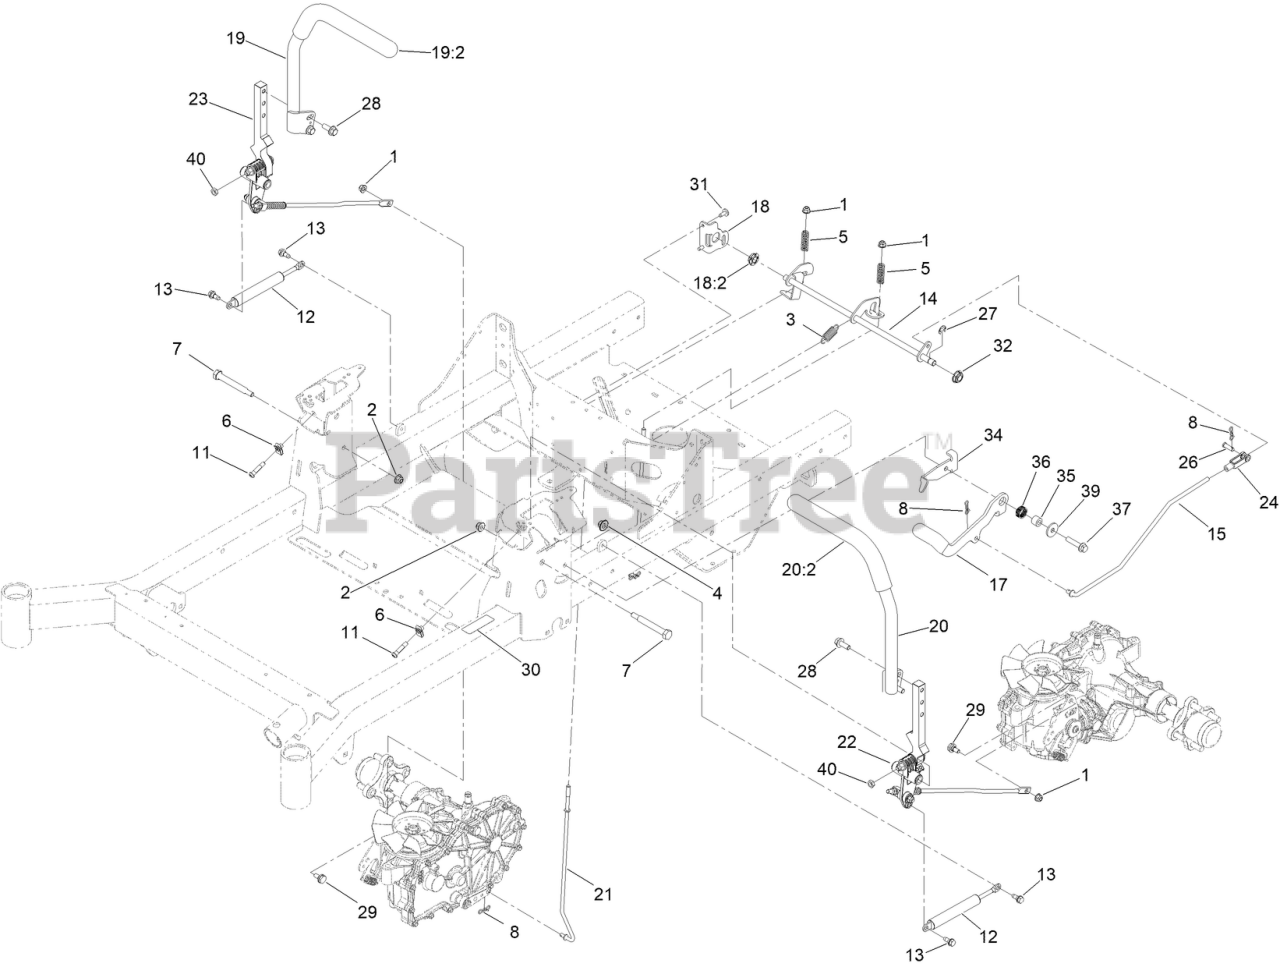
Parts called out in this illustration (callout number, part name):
1	NUT-HF, NI
2	NUT-HF, NI
3	SPRING-EXTENSION
4	NUT-FLANGE, NI
5	SPRING-COMPRESSION
7	BOLT-PIVOT
8	PIN-COTTER, LOCKING
11	SCREW-HSBH
12	DAMPER
13	SCREW-SHOULDER
14	SHAFT-BRAKE
15	LINKAGE-BRAKE, UPPER
17	LEVER-BRAKE (WITH GRIP)
18	BRACKET-BRAKE
18:2	BEARING-SPHERICAL
19	RH EXTENDED CONTROL HANDLE ASM
20	LH EXTENDED CONTROL HANDLE ASM
21	LINKAGE-BRAKE, LOWER
22	LH MOTION CONTROL ASM
23	RH MOTION CONTROL ASM
24	YOKE-ADJUSTABLE
26	PIN-CLEVIS
27	RING-RETAINING, EXTERNAL
28	SCREW-HHF
29	BOLT-SHOULDER,HFH
30	DECAL-BRAKE INTL
31	SCREW-TORX
32	BEARING-SPHERICAL
34	BRACKET-BRAKE
35	BUSHING
36	SPRING-WAVE
37	SCREW-HHF
39	WASHER
40	NUT-JAM
